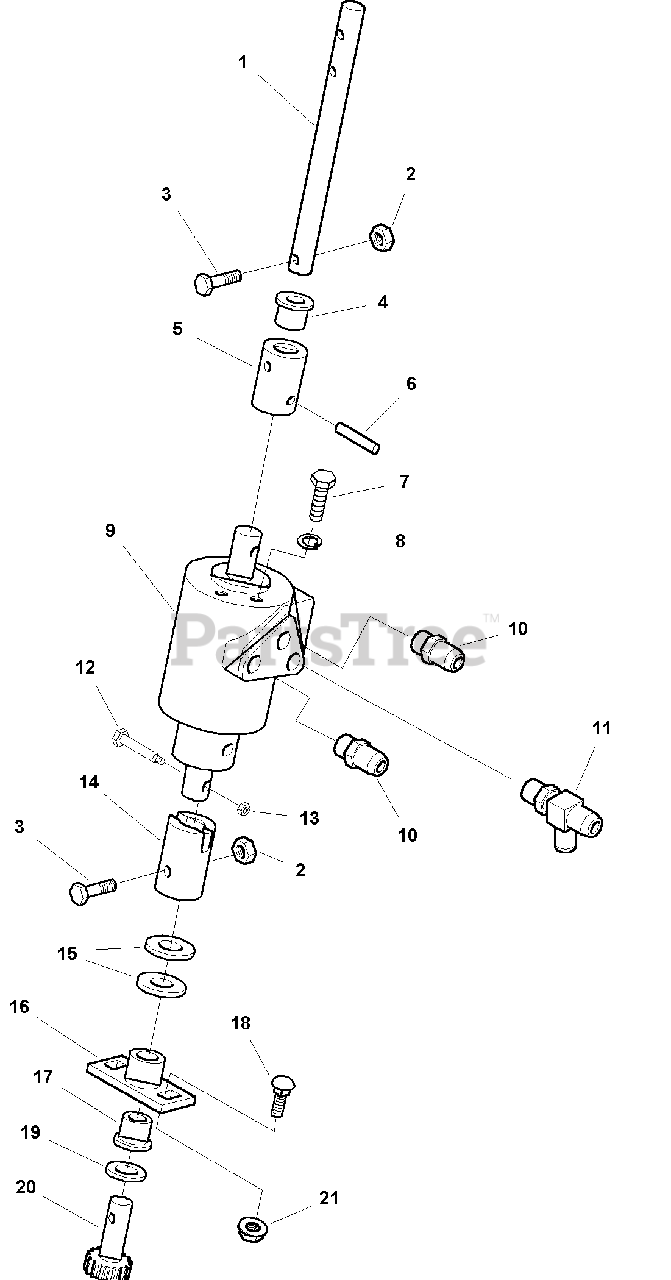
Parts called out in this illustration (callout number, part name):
1	SHAFT, Steering
2	LOCKNUT, 5/16-18
3	CAPSCREW, Hex Head 5/16-18 x 2 G5
4	BUSHING, Nylon
5	COUPLING, Upper
7	CAPSCREW, Hex, Head, 5/16-18 x 3/4
8	LOCKWASHER, 5/16
9	TORQUE GENERATOR
10	FITTING, Male
11	FITTING, "T"
12	SHOLDER BOLT, Hex Head, 1/4-20
13	NUT, Hex, Centerlock, 1/4-20
14	COUPLING, Lower
15	WASHER, Lower Shaft
16	PLATE ASSEMBLY, Shaft Support
18	CARRIAGE BOLT, 3/8-16 x 1
19	WASHER, 3/4
20	SHAFT & PINION ASSEMBLY
21	LOCKNUT, Flange, 3/8-16
